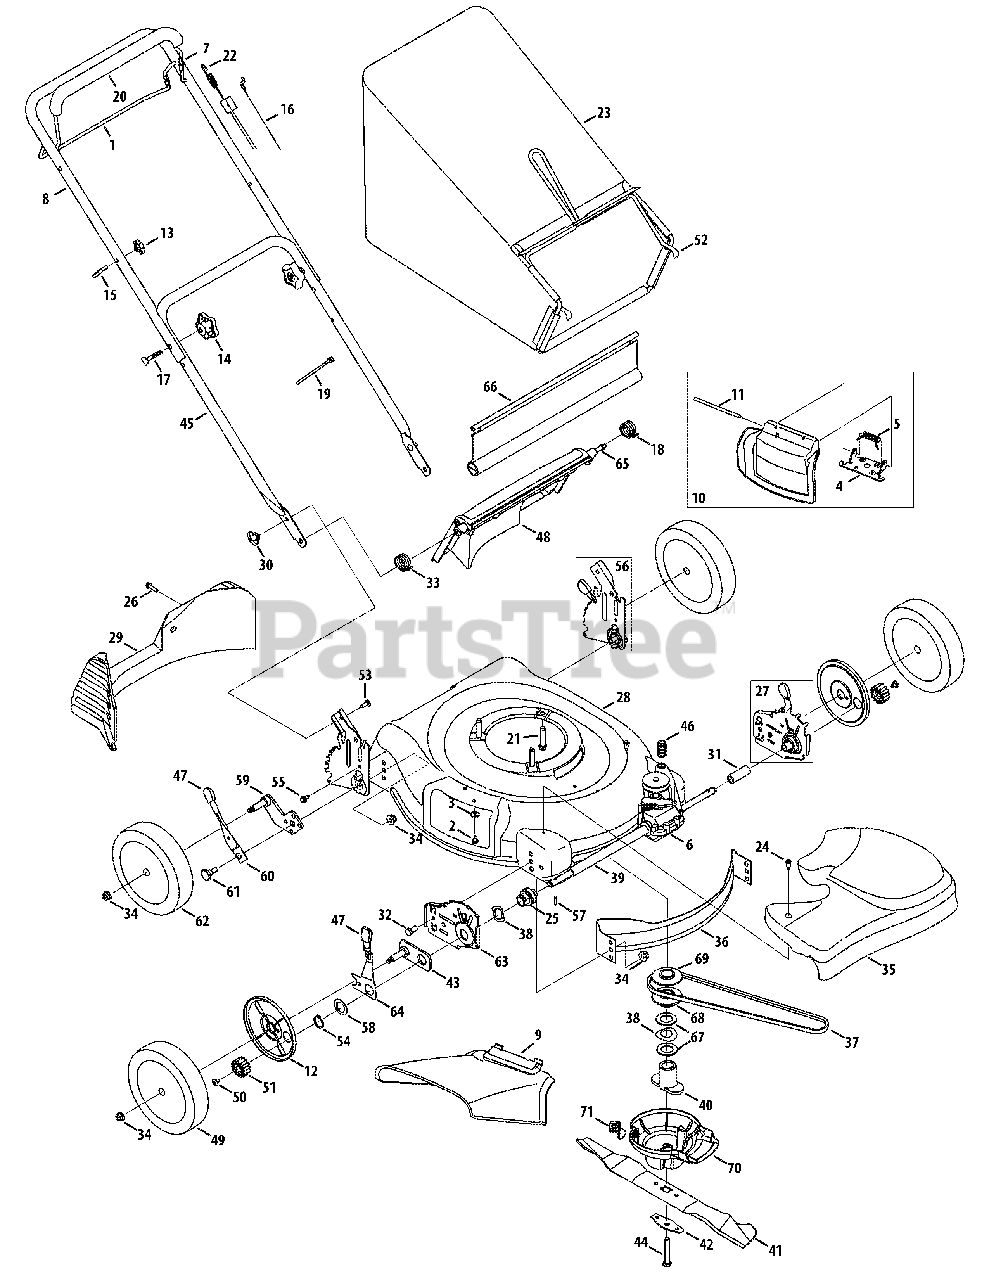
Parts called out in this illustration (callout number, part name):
1	Drive Control
2	TT Screw 1/4-20 x .05
3	Bell Washer .265 x .075
4	Deflector Chute Adapter
5	Torsion Spring
6	Transmission Assembly
9	Chute Deflector
10	Mulch Plug Complete
11	Hinge Pin
12	Wheel Dust Cap
13	Handle Knob
14	Star Knob
16	Control Cable 40.75''
17	Carriage Bolt 5/16-18 x 2.0
18	Torsion Spring - LH
19	Cable Tie
20	Bail Cover
21	Self-Tapping Sems Screw
22	Drive Cable 51''
23	Grass Bag
24	Shoulder Screw #12-24
25	Front Bearing Assembly
26	Screw, 1/4-15 x 1.000
27	Height Adjustment Assembly - RH
27	Height Adjustment Assembly - LH
30	Wing Nut
31	Sleeve Spacer 1.4''
32	Hex Screw, 3/8-16 x .75
33	Torsion Spring - RH
34	Flange Lock Nut, 3/8-16
35	Transmission Cover
36	Front Baffle
37	V-Belt
38	Wave Washer
39	Sleeve Spacer 8.985''
40	Blade Adapter, 25mm
41	21'' Mulching Blade
42	Blade Bell Support
43	Pivot Plate Assembly
44	Hex Screw, 3/8-24 x 2.50
46	Belt Tension Spring
47	Adjustment Knob
48	Rear Discharge Door
49	Front Wheel
50	Screw, 1/4-20 x .390
51	Gear 14T RH FWD
51	Gear 14T LH FWD
53	Carriage Bolt, 1/4-20
54	Snap Ring
55	TT Screw w/Washer 1/4-20 x .625
56	Handle Bracket Assembly - RH
56	Handle Bracket Assembly - LH
57	Dowel Pin
59	Pivot Arm Assembly - RH
59	Pivot Arm Assembly - LH
60	Rear Spring Lever
61	Shoulder Screw .500 Dia x .434
62	Rear Wheel
63	Height Adjuster Plate - RH
63	Height Adjuster Plate - LH
64	Front Lever - RH
64	Front Lever - LH
66	Rear Trailing Shield
67	Washer, Flat 1.031 x 1.620 x .095
68	Pulley, Half
69	Pulley, Half
70	Engine, Baffle
71	Engine, Baffle Bracket
